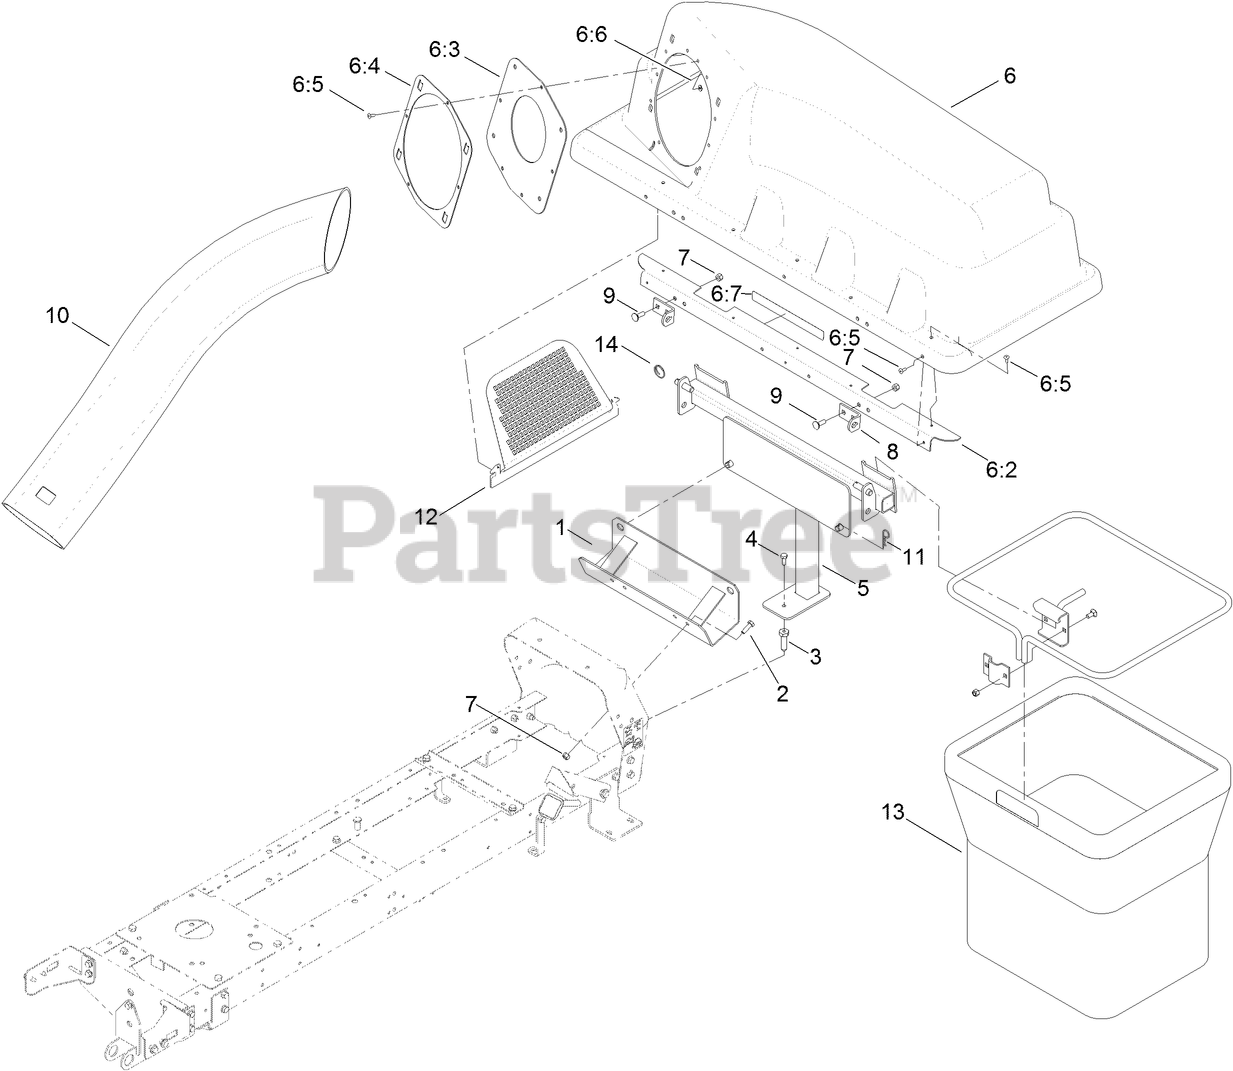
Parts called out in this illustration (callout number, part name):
1	BRACKET-CHANNEL
2	SCREW-HH
3	PIN-MOUNTING, LOWER
4	SCREW-HH
5	FRAME ASSEMBLY, BAGGER
6	COVER-TWIN BAGGER
6:2	STIFFENER-BAGGER TOP
6:3	GASKET-BAGGER COVER
6:4	RING-RETAINER
6:5	RIVET-BLIND
6:6	WASHER-FLAT
6:7	DECAL-CAUTION BAGGER
7	NUT-LOCK, NI
8	BRACKET-PIVOT, HOPPER
9	BOLT-CARR
10	CHUTE-BAGGER
11	PIN-HAIR
12	SCREEN-BAGGER
13	BAG ASM
14	PIN-COTTER, CIRCULAR
